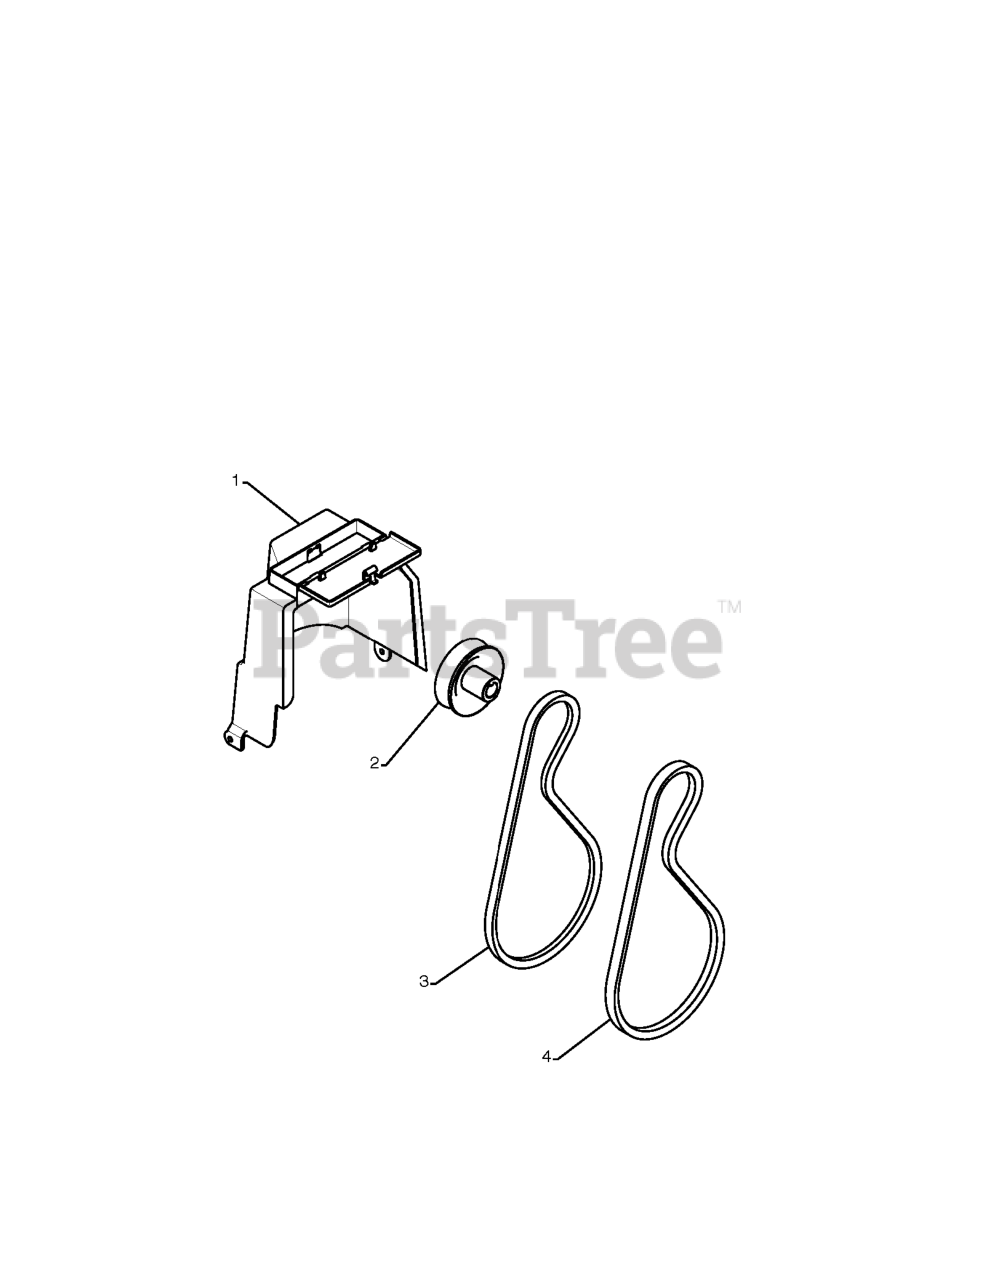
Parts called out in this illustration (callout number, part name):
1	COVER.BELT.HS
2	PULLEY.ENG.IMPELLER.SNOW
3	V-BELT.TRACTION.HYDRO
4	VBELT; IMPELLER_39.09
